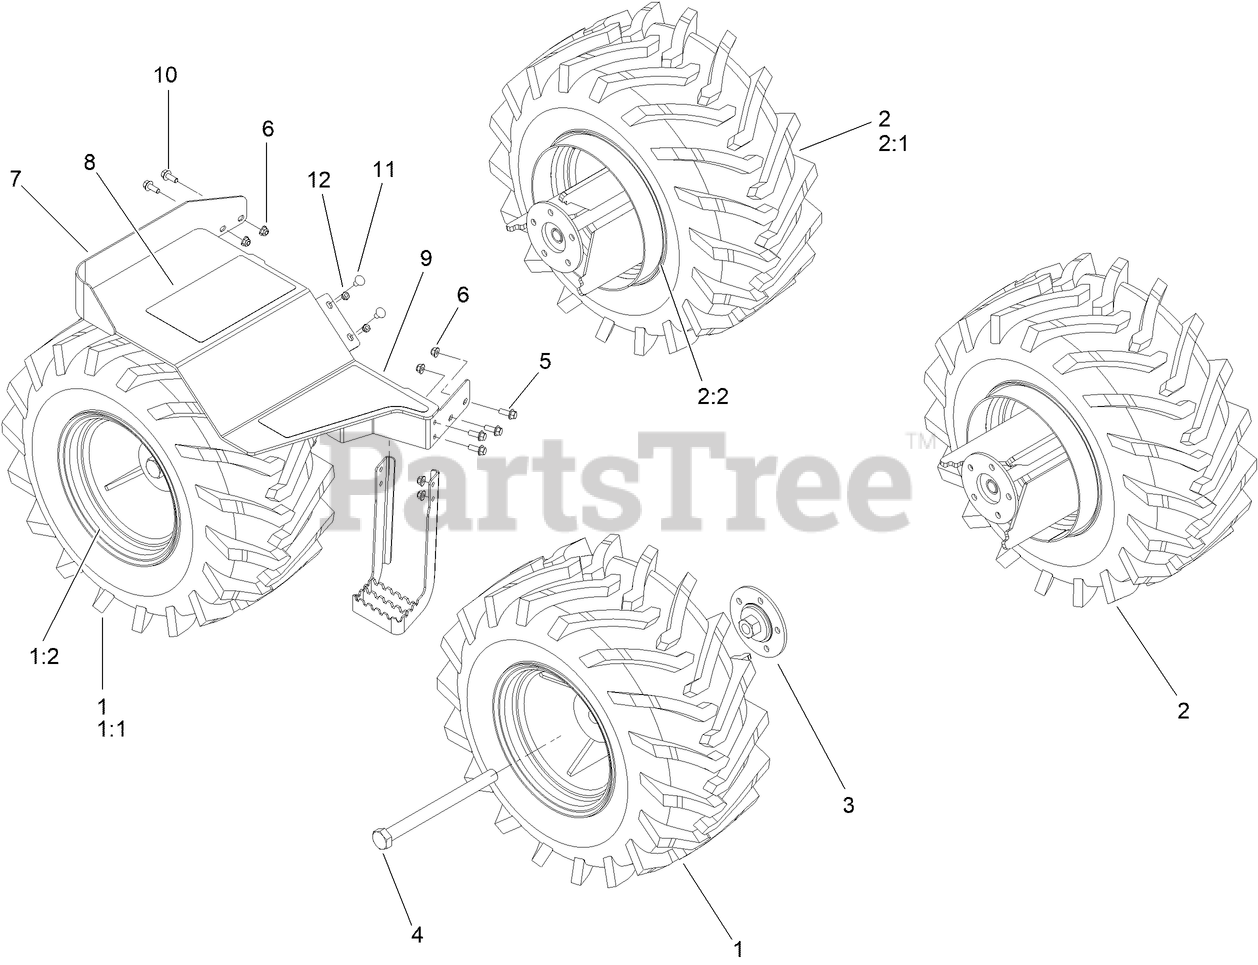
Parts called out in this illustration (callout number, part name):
1	RH DUAL 26IN WHEEL ASM
1:1	TIRE (26 X 12-12, 8-PLY, TL)
1:2	WHEEL-DUAL
2	LH DUAL 26IN WHEEL ASM
2:1	TIRE (26 X 12-12, 8-PLY, TL)
2:2	WHEEL-DUAL
3	PLATE - RETAINER DUAL WHEEL
4	SCREW-HH
5	SCREW-HHF
6	NUT-HF, NI
7	PLATFORM-EXTENSION DUAL 26"
8	NON-SKID
9	NON-SKID
10	SCREW-HHF
11	SCREW-CARR
12	NUT-HEX
